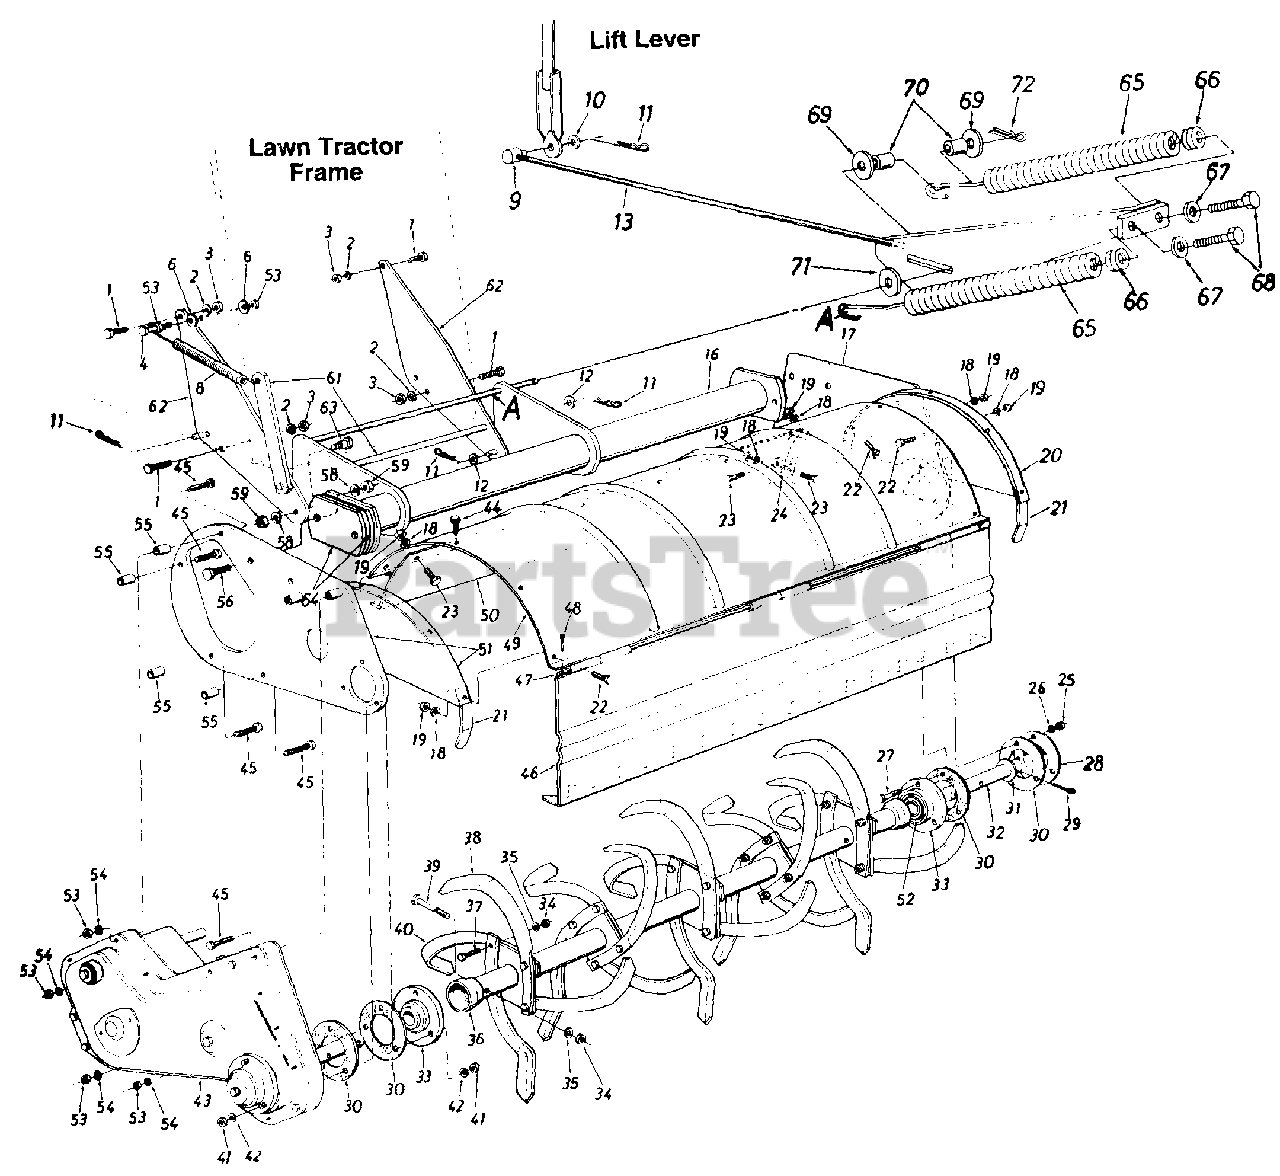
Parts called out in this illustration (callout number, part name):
1	Hex Bolt 3/8-24 x .88" Lg.
2	L-Wash. 3/8" I.D. - H.D.
3	Hex Nut 3/8-24 Thd.
4	Hex Bolt 1/4-20 x 1.25" Lg.
6	Bell-Wash. 1/4" I.D.
8	Ext. Spring 7.75" Lg.
9	Adjustment Ferrule 1/2-13 Thd.
10	Fl-Wash. .64" I.D. x 1.24" O.D. x .06"
11	Intern. Cotter Pin 1/2" Dia.
12	Fl-Wash. .51" I.D. x 1.0" O.D. x .06"
13	Lift Bracket Ass'y.
14	Comp. Spring 1.5" O.D. x 15" Lg.
15	Fl-Wash. .51" I.D. x 1.5" O.D. x .075"
16	Pivot Bracket Assembly
19	Hex Nut 5/16-24 Thd.
23	Hex Bolt 5/16-24 x .62" Lg.
24	Chute Pivot Bracket
25	Hex L-Nut 5/16-18 Thd.
27	Hex Bolt 5/16-18 x 1" Lg. (Grade 5)
30	Gasket for Brg. Housing
31	Fl-Wash. 1.25" I.D. x 2.0" O.D. x .06"
32	Tine Shaft 1.25" Dia. x 6.25" Lg.
33	Bearing Housing w/Bearing
38	Tine 14" x 5/16"
39	Hex Bolt 3/8-24 x 2.25" Lg.
40	Tine 14" x 5/16"
43	Chain Case Ass'y. Comp.
44	Hex TT-Tap Scr. 5/16-18 x .62" Lg.
45	Hex Bolt 1/4-20 x 2.75" Lg.
48	Cotter Pin 1/8" Dia. x 1" Lg.
53	Hex Nut 1/4-20 Thd.
54	L-Wash. 1/4" I.D.
55	Spacer .28" I.D. x .62" O.D. x .9" Lg.
56	Hex Bolt 1/2-20 x 1.5" Lg.
58	L-Wash. 1/2" I.D.
59	Hex Nut 1/2-20 Thd.
61	Idler Brkt. Support Arm Ass'y.
62	Pivot Brkt. Support
63	Shoulder Bolt
64	Support Plate
65	Helper Spring
66	Spring Insert
67	Fl-Wash. .34" I.D. x .68" O.D.
68	Hex Bolt 5/16-18 x 3.25" Lg.
69	Fl-Wash. .51" I.D. x 1.5" O.D.
70	Split Spacer .505" I.D. x .57" Lg.
71	Fl-Wash. .531" I.D. x 1.25" O.D.
72	Internal Cotter Pin 1/2" Dia.
